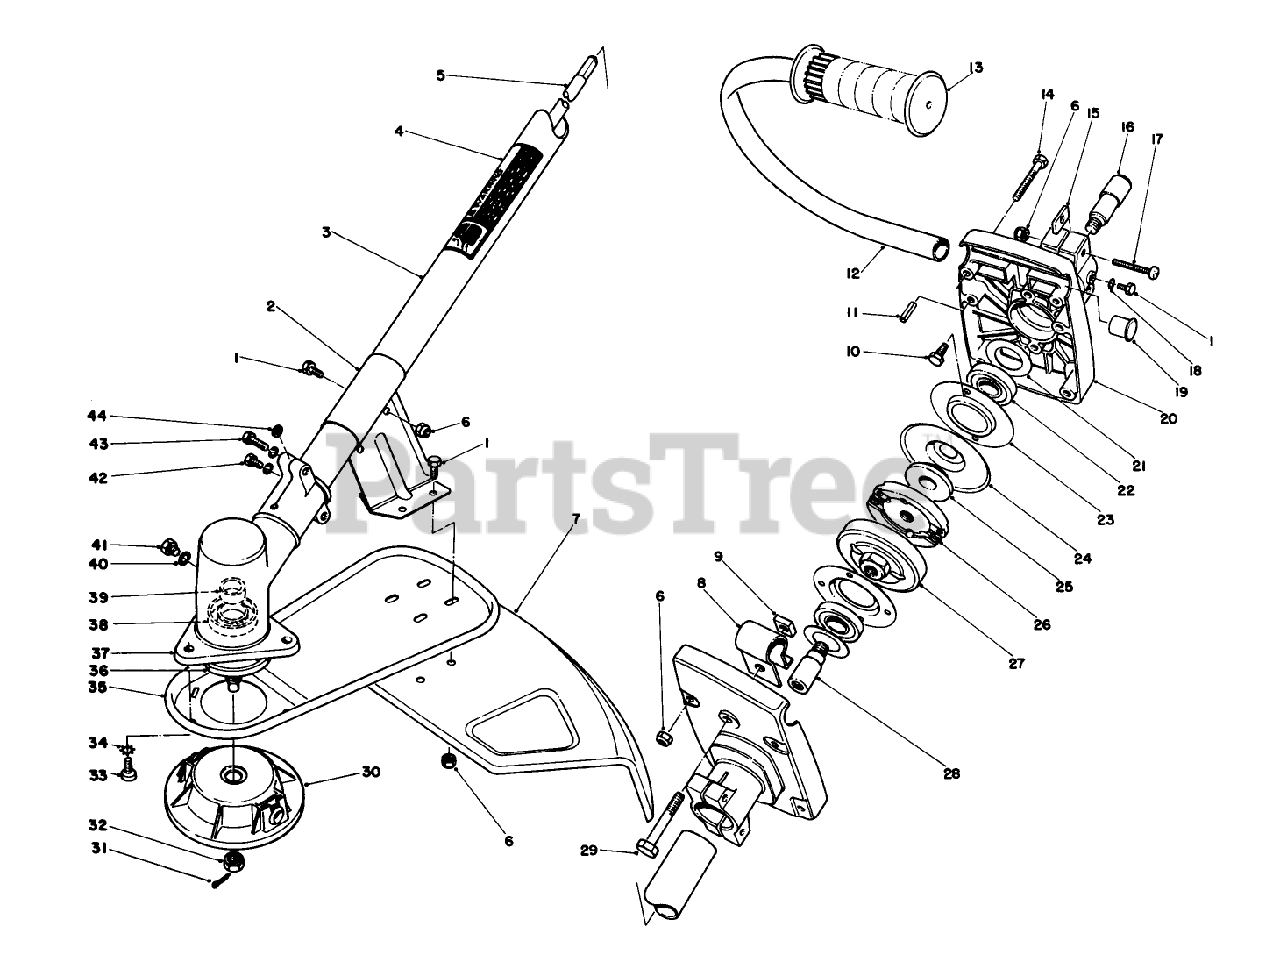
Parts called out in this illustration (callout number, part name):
1	SCREW-SHH
2	SHIELD BRKT
5	Drive Shaft
6	NUT-LOCK, NI
9	Nut-Square
10	SCREW-TAPTITE
11	PIN-SPRING
18	WASHER-LOCK/SP
21	FLAT WASHER
22	BEARING-BALL
29	45050-T/ST FRENCH 2
30	CUTTER HEAD-PLASTIC
31	PIN-COTTER
33	SCREW
34	WASHER-LOCK, EXT
35	SHIELD SUPPORT *R
36	DUST CAP F/W
38	OIL SEAL
42	HHMS SCREW
